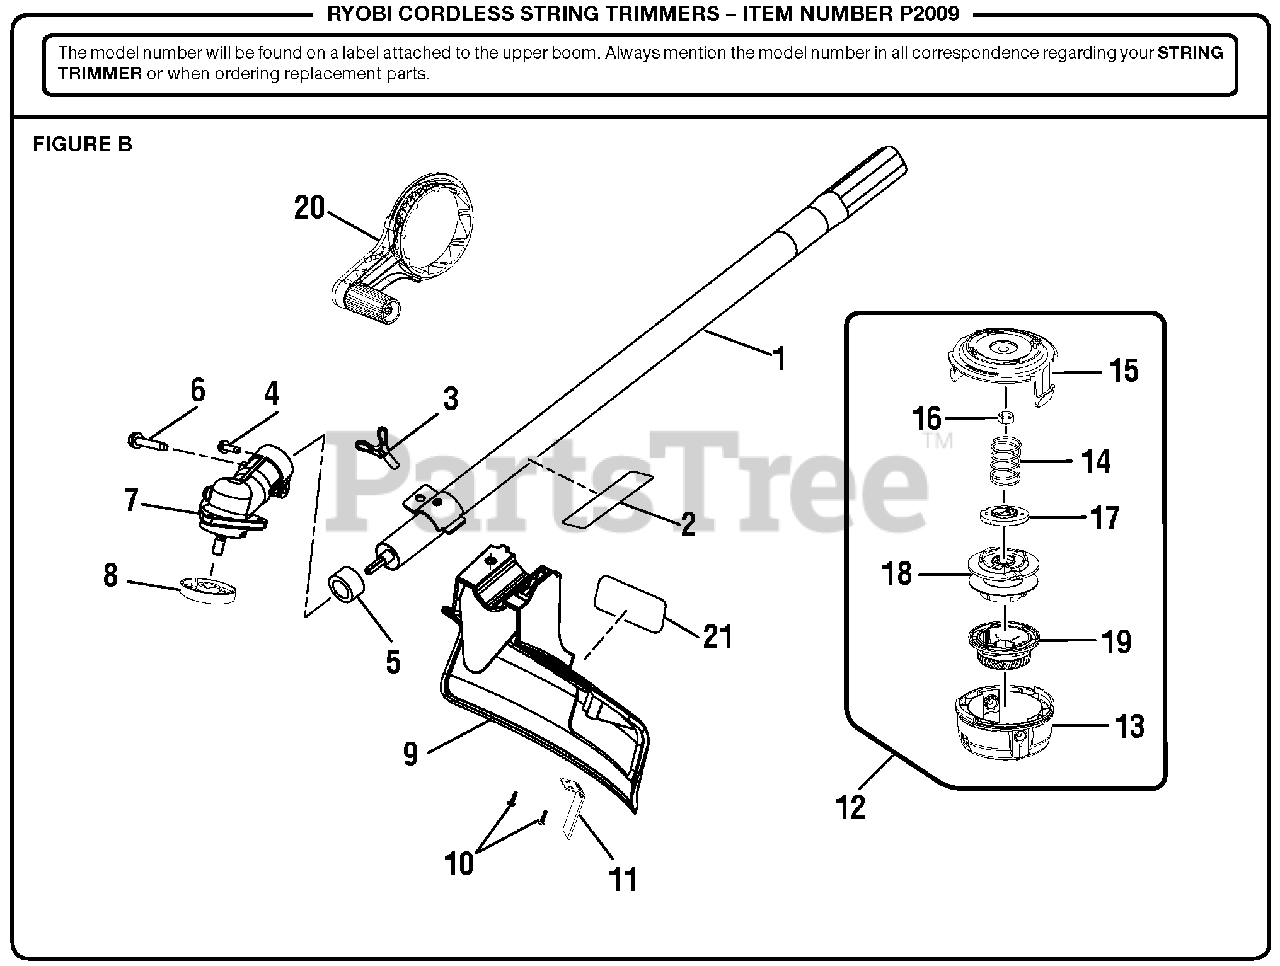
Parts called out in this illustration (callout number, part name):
1	Lower Boom Assembly
2	Logo Label (Shaft)
3	Wing Screw
4	Screw (10-24 x 5/8in., Hex Washer Hd. S.T.)
6	Screw (1/4-20 x 1-1/4 in., Hex Washer Hd. S.T.)
7	Gear Head Assembly
8	Flanged Washer
9	Grass Deflector Assembly
10	Screw (M4 x 12 mm)
11	Line Cut-Off Blade
12	Trimmer Head Assembly (.080)
13	Lower Housing
15	Upper Housing
17	String Guide
18	Spool Assembly
19	Bump Knob (Green)
20	Crank Handle Assembly
21	Logo Label (Guard)
